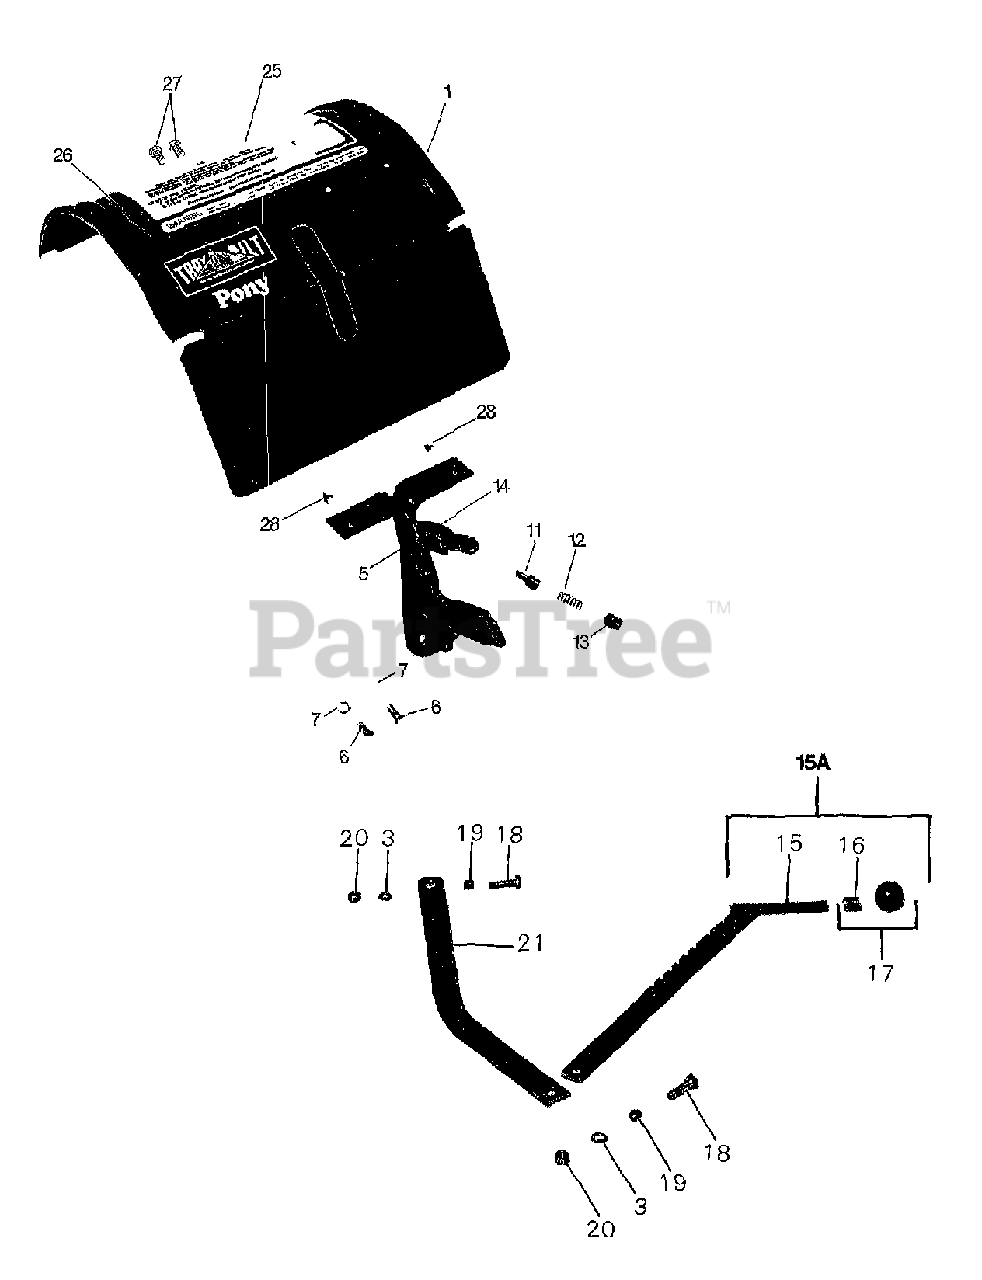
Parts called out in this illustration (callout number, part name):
1	HOOD-tine cover, with hinged flap
3	LOCKWASHER- 3/8"
5	BRACKET-hood & depth regulator,
6	BOLT-hex head, 5/16-18 x 3/4" (bracket to rear bearing cap)
7	LOCKWASHER-5/16"
11	PLUNGER-depth regulator locking
12	SPRING-depth regulator plunger
13	PLUG -pipe, 1/4"
14	ROLL PIN-1/4" x 1"(spiral)
15	BAR- depth adjustment
15A	BAR ASSEMBLY-depth adjustment
16	RING- retaining, tolerance ring
17	KNOB-depth regulator,
18	BOLT- hex head, 3/8"-16 x 1 1/4"
19	BUSHING-spacer, drag bar
20	NUT-hex, 3/8-16
21	DRAG BAR-depth regulator
25	DECAL-tiller operation instructions
26	DECAL-Troy-Bilt Pony (model name decal)
27	SCREW-hex head, 5/16"-18 x 1/2" self-tapping
28	SCREW-flanged hex head, 1/4"-20 x 1/2" self-tapping (attaches hood to depth regulator bracket)
